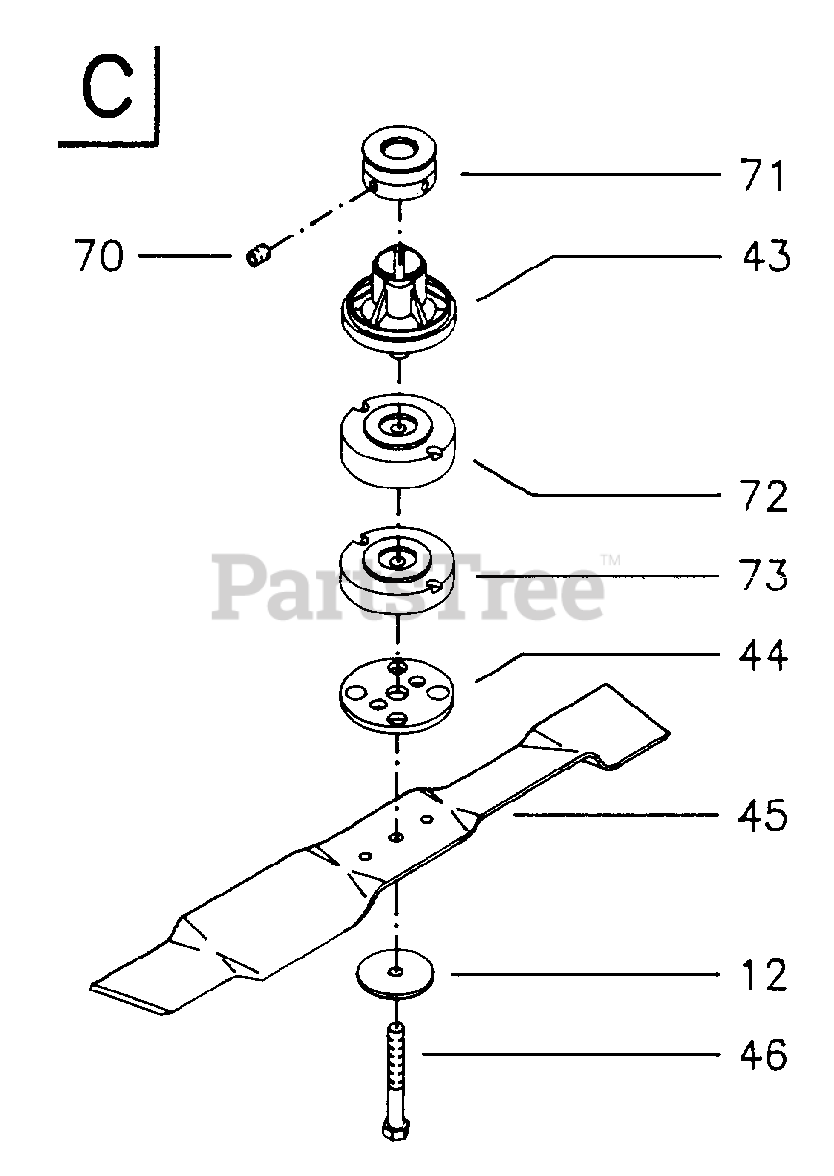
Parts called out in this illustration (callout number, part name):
44	STEEL PLATE ADAPTER
72	SPACER
73	SPACER
